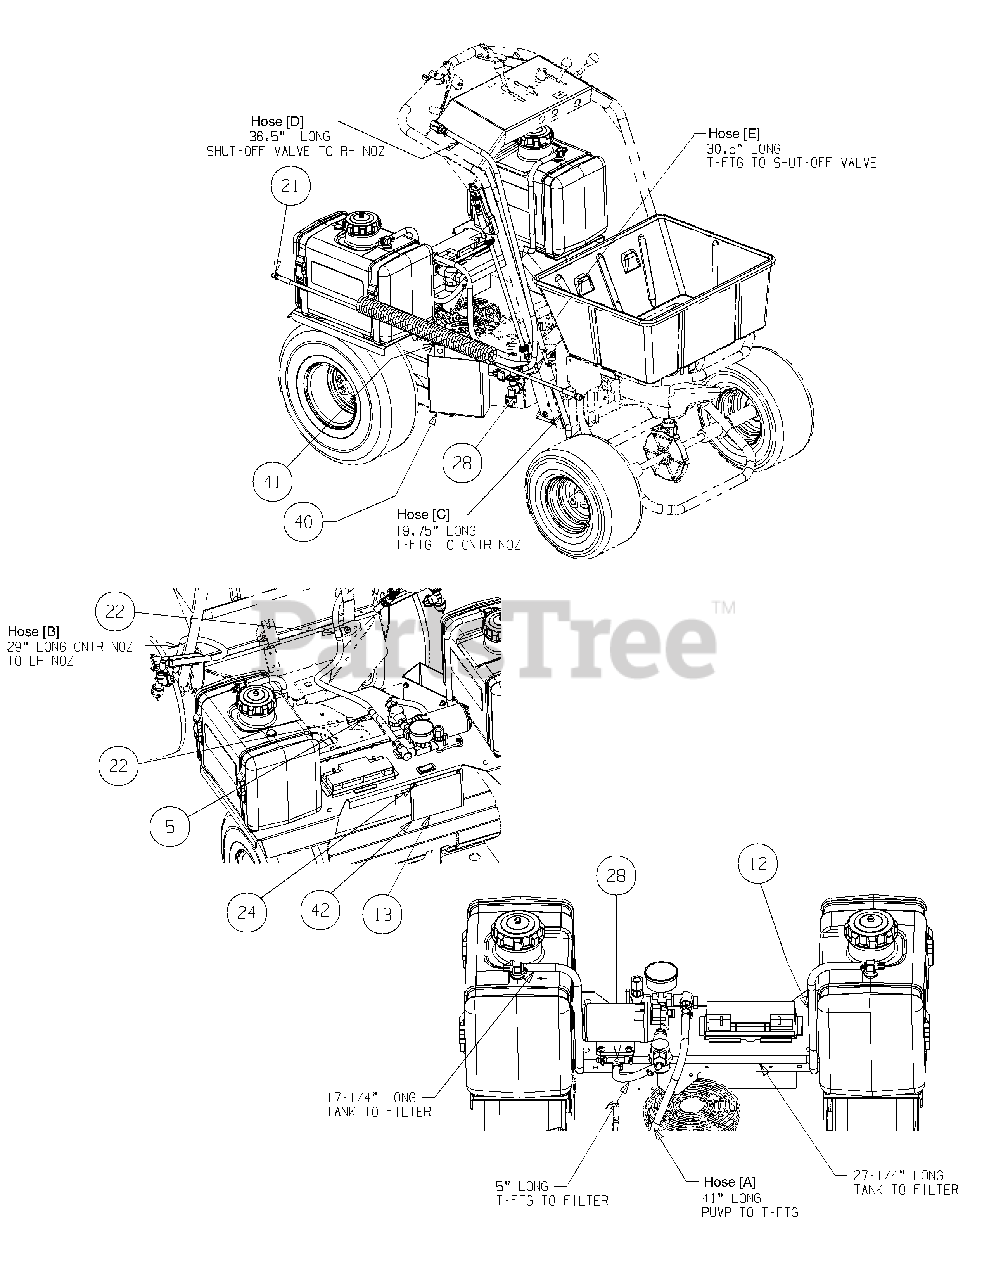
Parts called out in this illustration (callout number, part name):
5	Washer, 1/4
12	Hose, 3/8 x 17.20ft - 300psi
13	Decal, Safety Procedures
21	Hose Assembly, 25ft blue
24	Self Tapping Screw, #10-24 x 0.500
28	Tee Fitting, 3/8 Multi Barb
42	Bracket, Label
